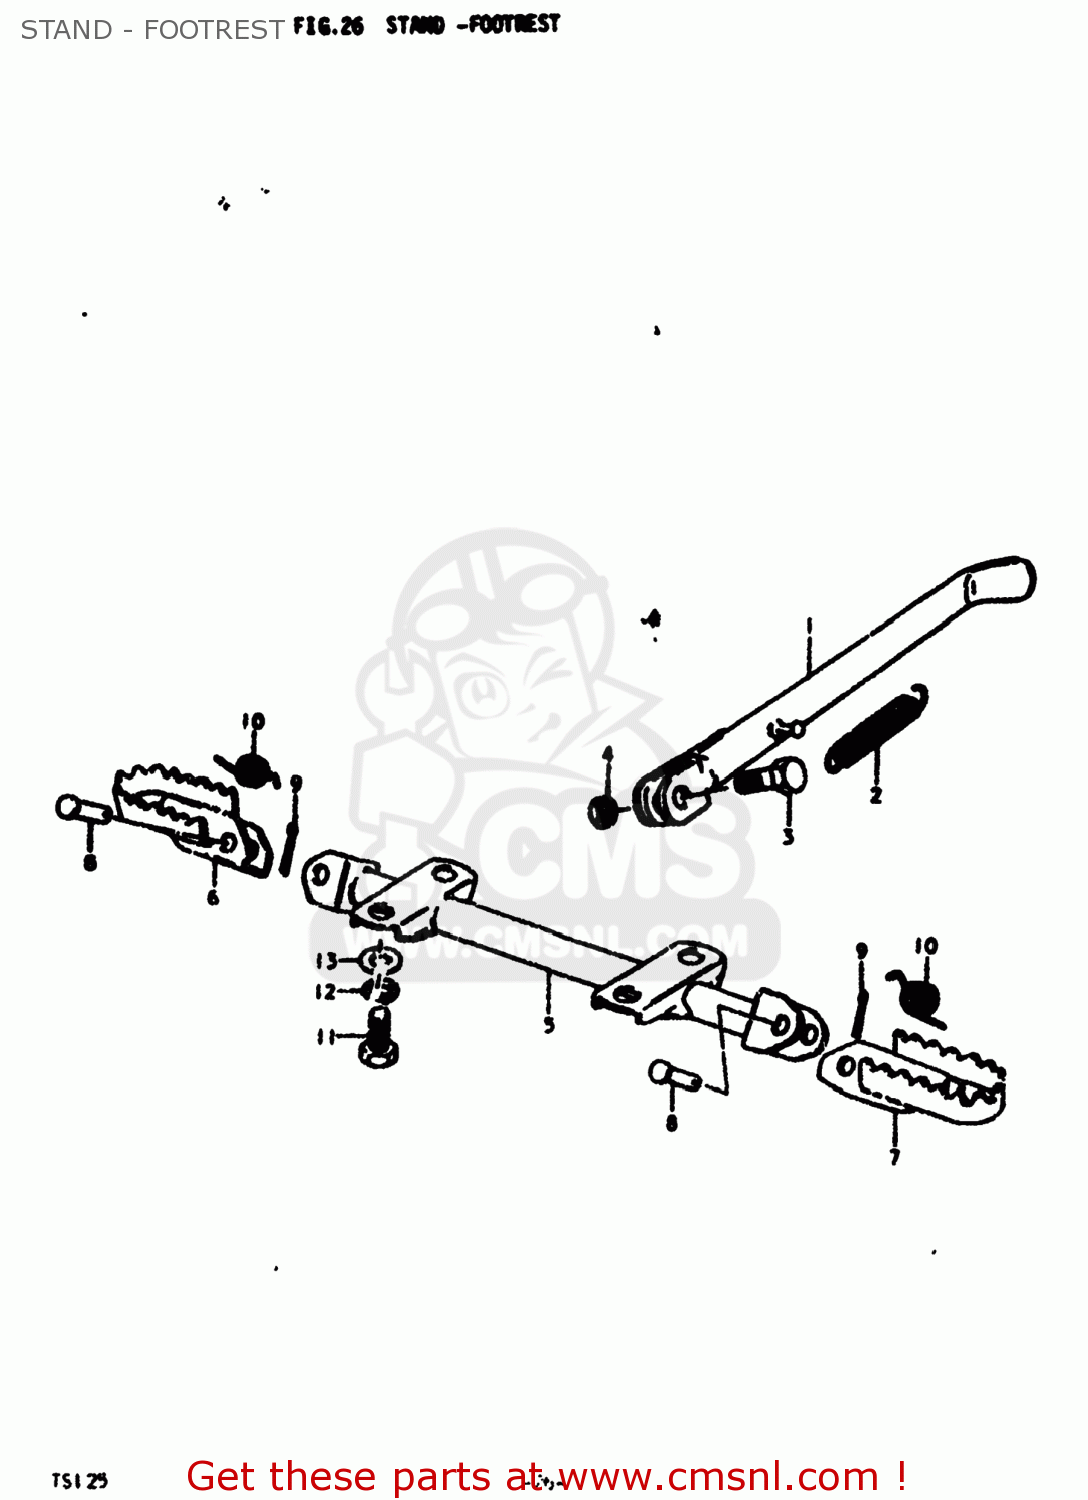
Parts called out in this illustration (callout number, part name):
1	STAND,SIDE
2	SPRING
3	BOLT(10X30)
4	NUT
5	BAR,FR FOOTREST
6	FOOTREST,FR,R
7	FOOTREST,FR,L
8	PIN
9	PIN 20X20
10	SPRING
11	BOLT
12	LOCK WASHER
13	WASHER
